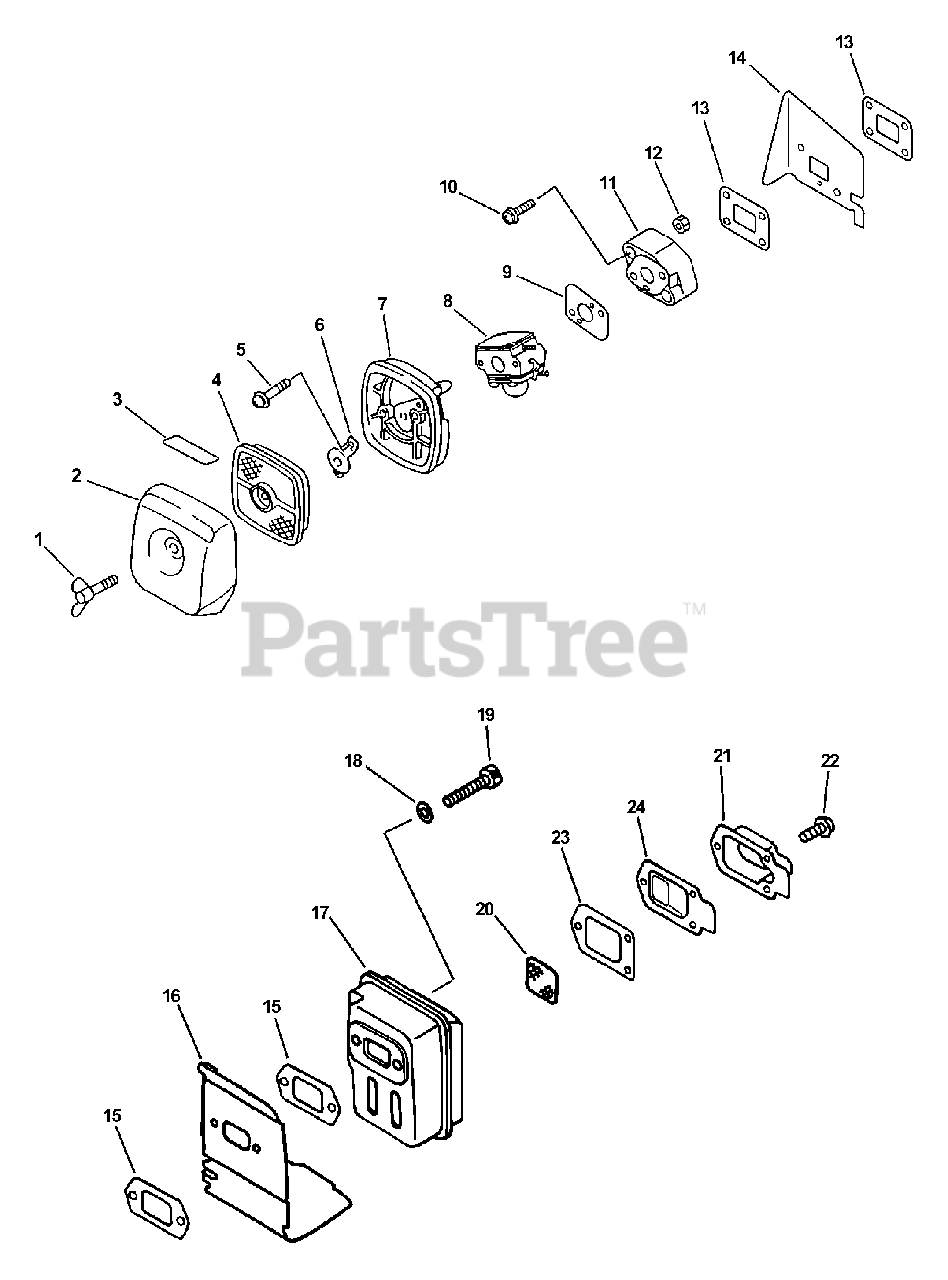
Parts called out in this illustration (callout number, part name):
1	THUMBSCREW
2	COVER, AIR FILTER - GRAY
3	LABEL - CHOKE
4	FILTER, AIR - SINGLE LAYER
5	SCREW - 5X65
6	PLATE, PREVENT
7	AIR FILTER CASE ASSY
8	CARBURETOR
9	GASKET, INTAKE
10	SCREW - 5X22
11	INSULATOR, INTAKE
13	GASKET, INTAKE
14	SHIELD, INTAKE
15	GASKET, EXHAUST
16	SHIELD, EXHAUST
18	WASHER - 5
19	SCREW - 5X55
20	SCREEN, SPARK ARRESTOR
21	GASKET, EXHAUST - INNER
22	SCREW - 4X10
23	GASKET, EXHAUST
24	GUIDE, EXHAUST
24	GUIDE, EXHAUST - OUTER
